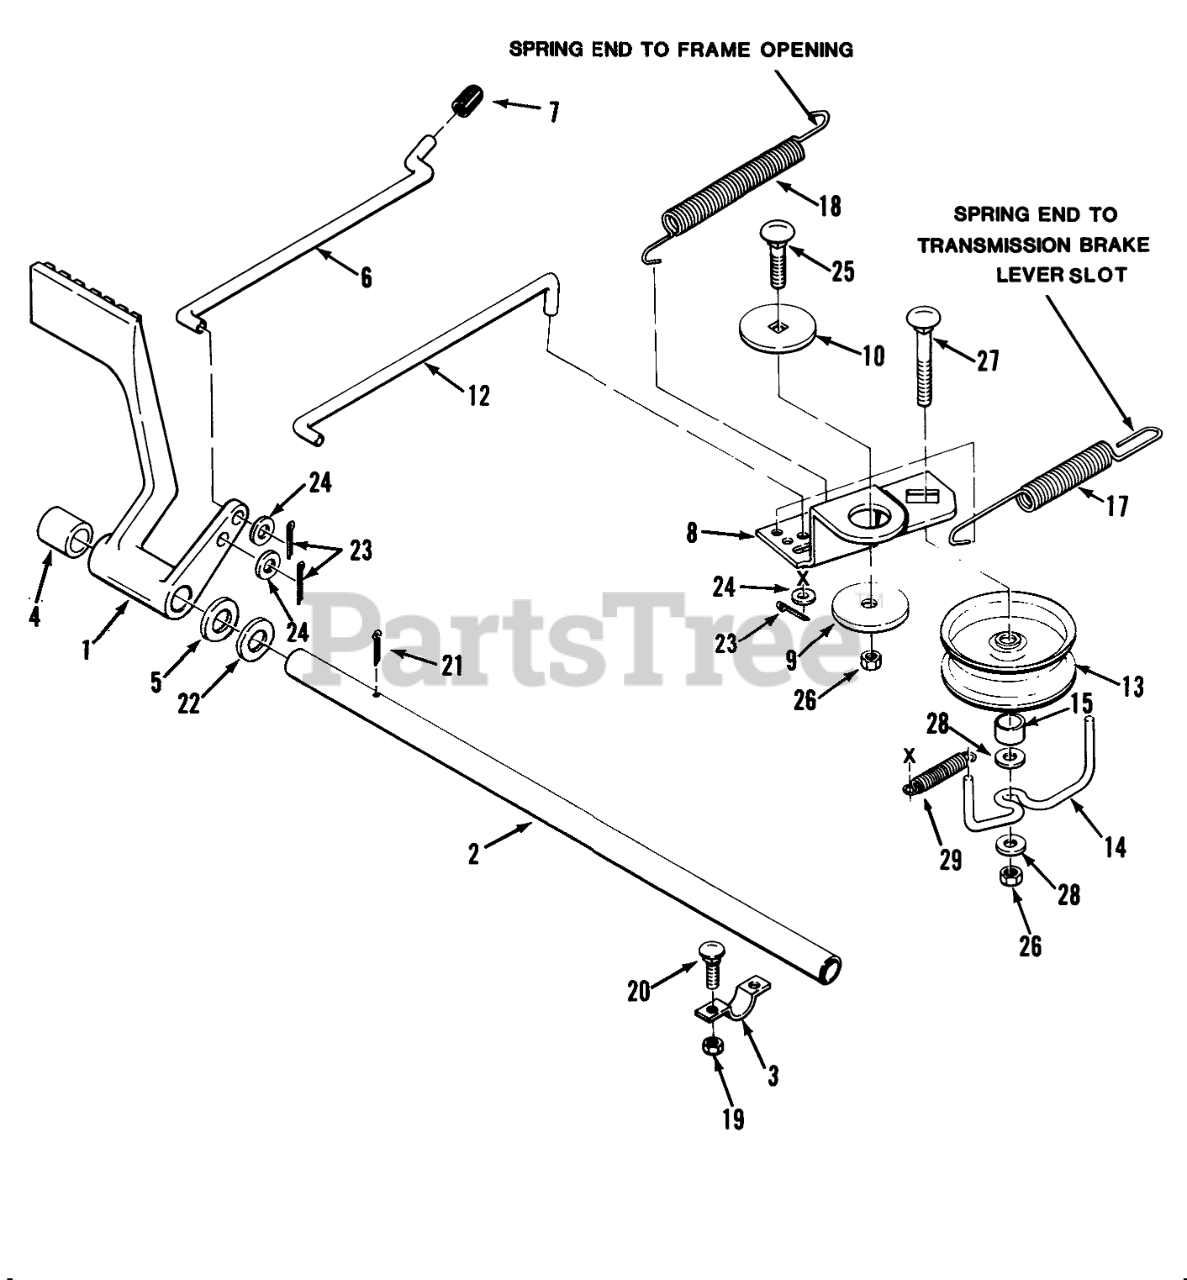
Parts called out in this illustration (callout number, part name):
1	PEDAL BRAKE R
2	SHAFT PEDAL
3	CLAMP
4	SPACER
5	WASHER-WAVE
6	Lock Rod
8	ARM-IDLER R
9	BUSHING
10	WASHER-BEARING
12	ROD-CLUTCH/BRAKE B
13	RETAINER R (NS)
14	GUIDE-BELT
15	SPACER
17	SPRING - BRAKE
18	SPRING - CLUTCH
19	Nut
20	Bolt
22	Washer
23	Cotter Pin
24	Washer
25	Bolt
26	NUT
27	Carriage Bolt 3/8-16 x 2-1/4
28	Washer
29	EXTENSION-SPRING
